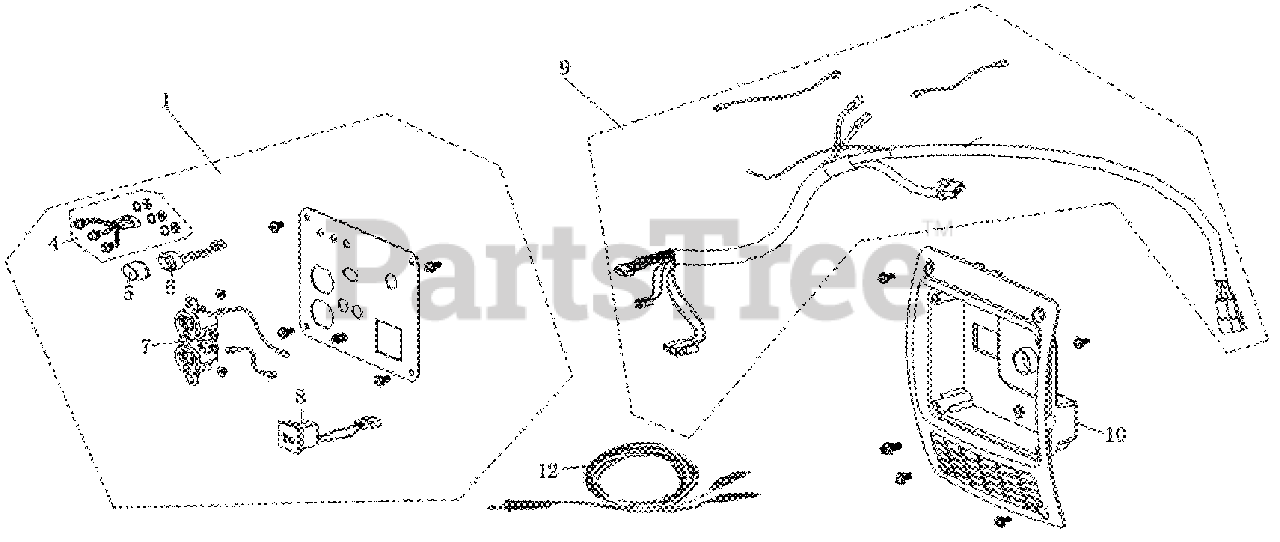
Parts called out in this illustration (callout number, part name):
1	CONTROL PANEL ASSY
4	LED INDICATOR LIGHT
5	COVER INSERT DEACTIVATN SWITCH
6	DEACTIVATION SWITCH
7	POWER SOCKET COMBINATION
8	DC SOCKET (WITH THE FLOW
9	CABLE ASSEMBLY
10	PANEL SEAT
12	CONNECTING LINE
